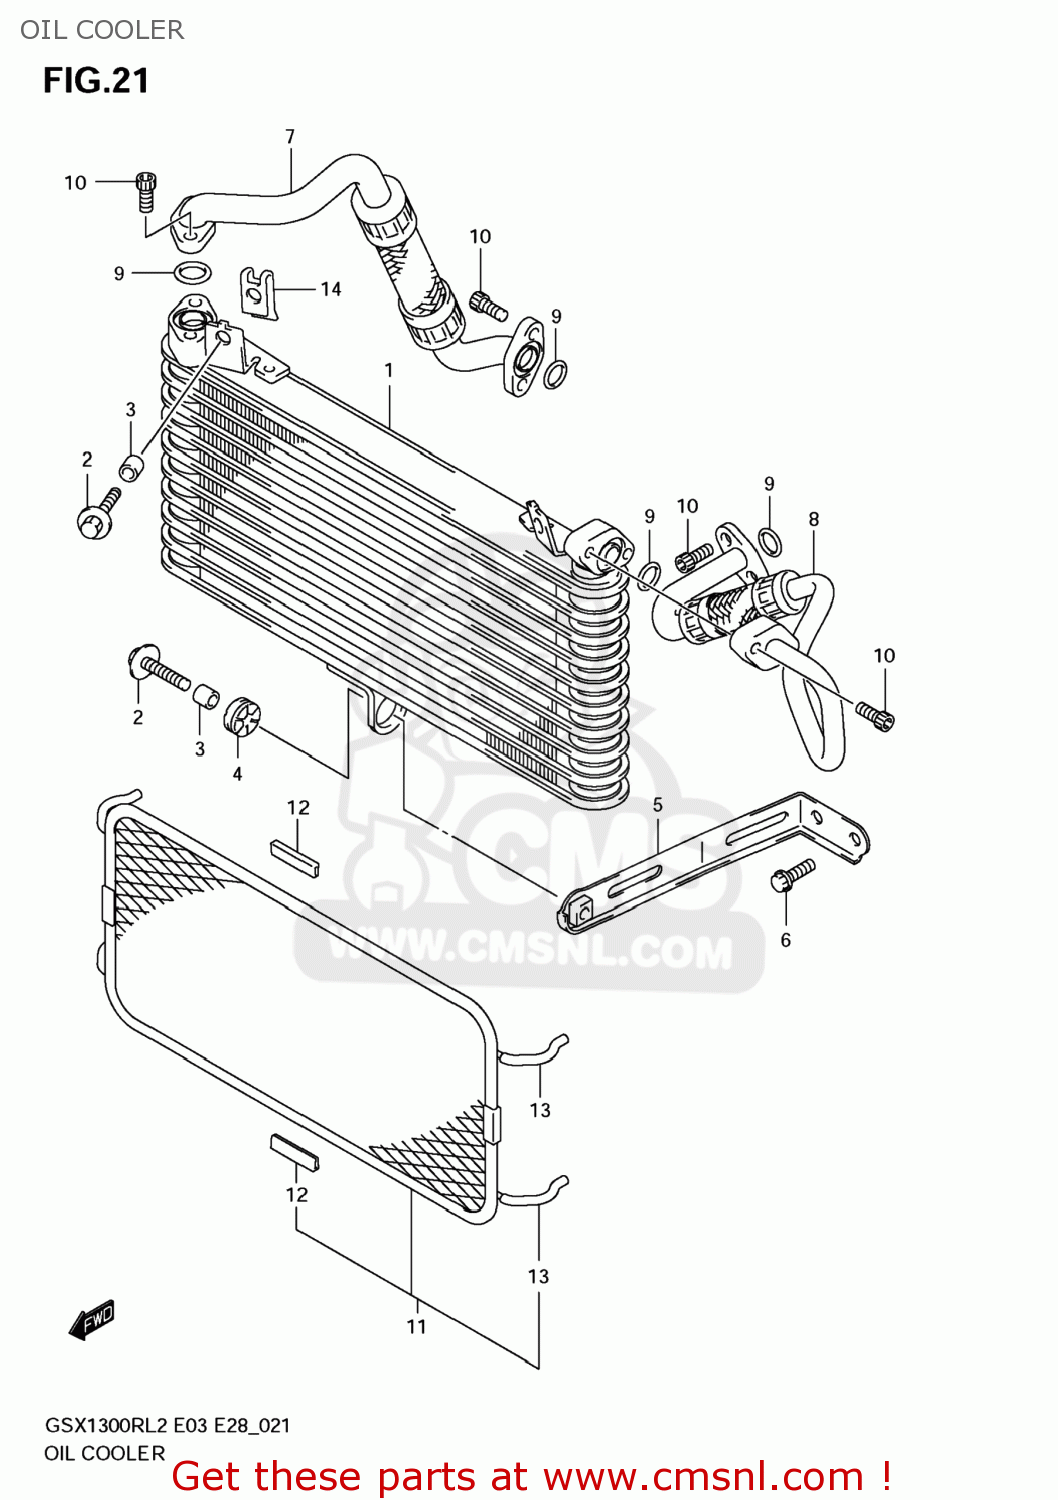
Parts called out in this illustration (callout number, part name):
1	COOLER ASSY,OIL
2	BOLT(6X25)
3	SPACER(6.5X10X12)
4	CUSHION
5	BRACKET,OIL COOLER
6	BOLT
7	HOSE,OIL COOLER,R
8	HOSE,OIL COOLER,L
9	O RING(D:2.4,ID:16)
10	BOLT(6X16)
11	GUARD,OIL COOLER
12	PROTECTOR,CTR
13	HOSE(3X5X600)
14	NUT,RADIATOR FAN
